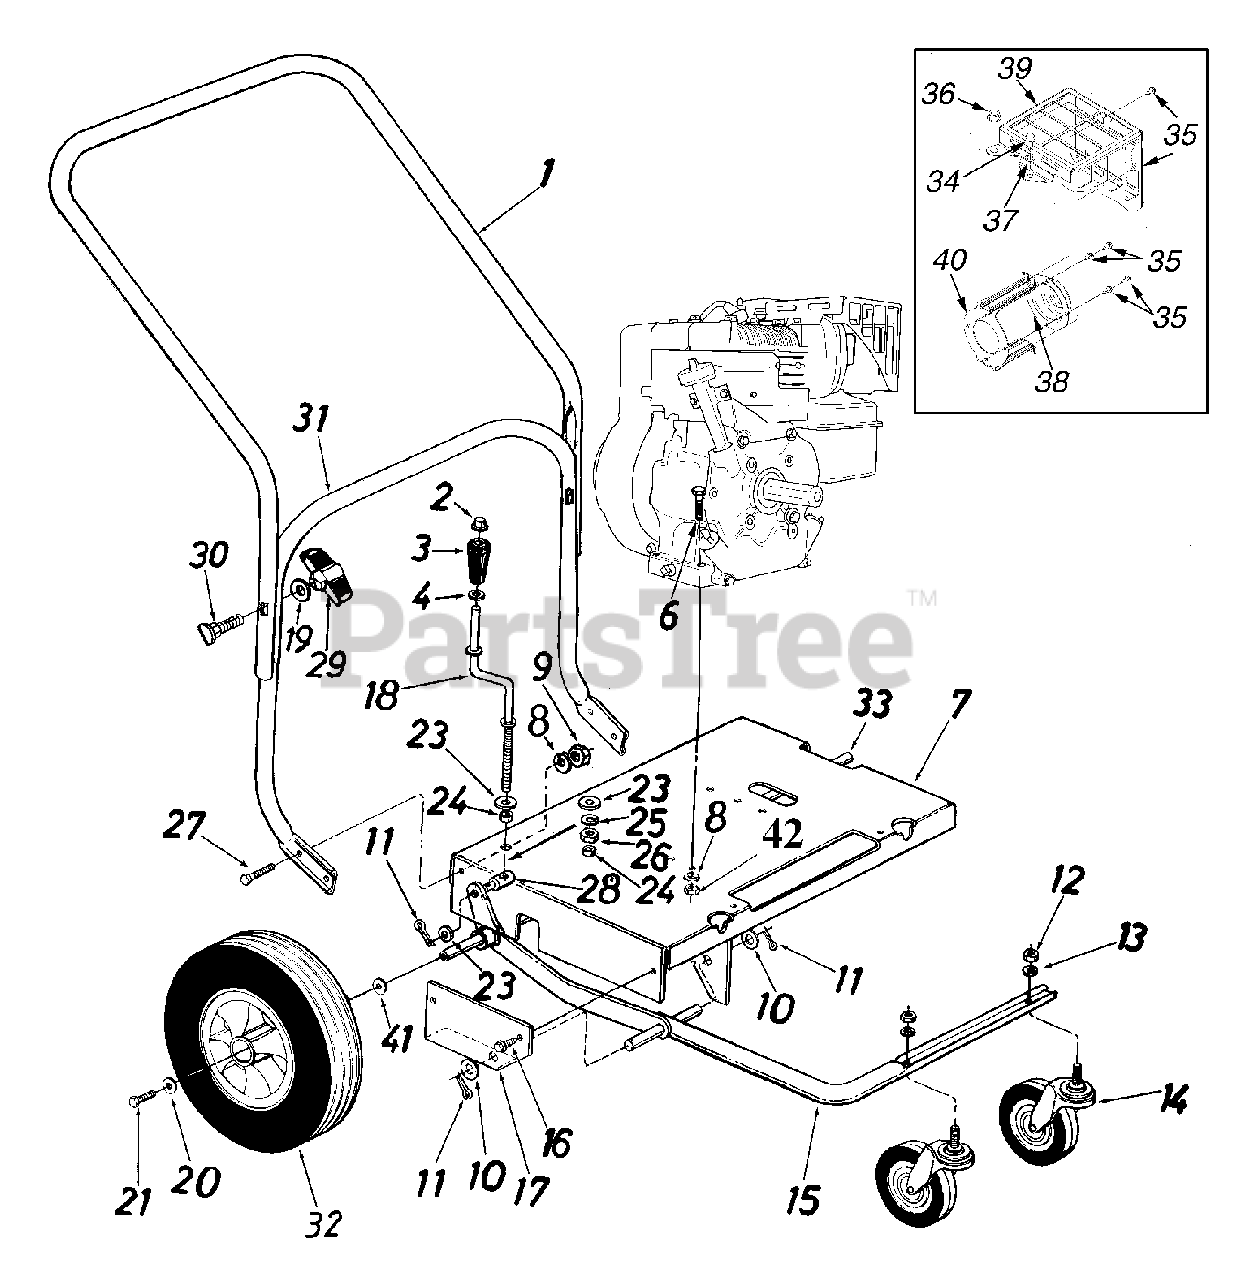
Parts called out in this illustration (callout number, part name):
2	Push Nut 3/8
3	Crank Knob
4	Flat Washer .385 ID x .62 OD
6	Hex Bolt 5/16-18 x 1.50
9	Hex Nut 5/16-18
10	Flat Washer .63 ID x 1.25
11	Cotter Pin
12	Hex Nut 1/2-13
13	Lock Washer 1/2
14	Swivel Caster Wheel 5" Dia x 1.25
19	Saddle Washer .32 ID x .93 OD
20	Flat Washer .34 ID x .87 OD
21	Hex Lock Bolt 5/16-24 x .64
23	Flat Washer .38 ID x .57 OD
24	Spacer .382 ID x .50 OD x .180Lg
25	Lock Washer 3/8 ID
26	Hex Nut 3/8-8
27	Hex Bolt 5/16-18 x .75
28	Ferrule
29	Hand Knob
30	Carriage Bolt 5/16-18 x 2.0
33	Rear Axle
34	Self Tap Screw 1/4-20 x .5
35	Screw 8-18 x .375
36	Hex Lock Nut 5/16-18
37	Lock Washer
38	Deflector
39	Muffler Guard
40	Muffler Guard Bracket
41	Flat Washer
42	Hex Lock Nut 5/16-18
